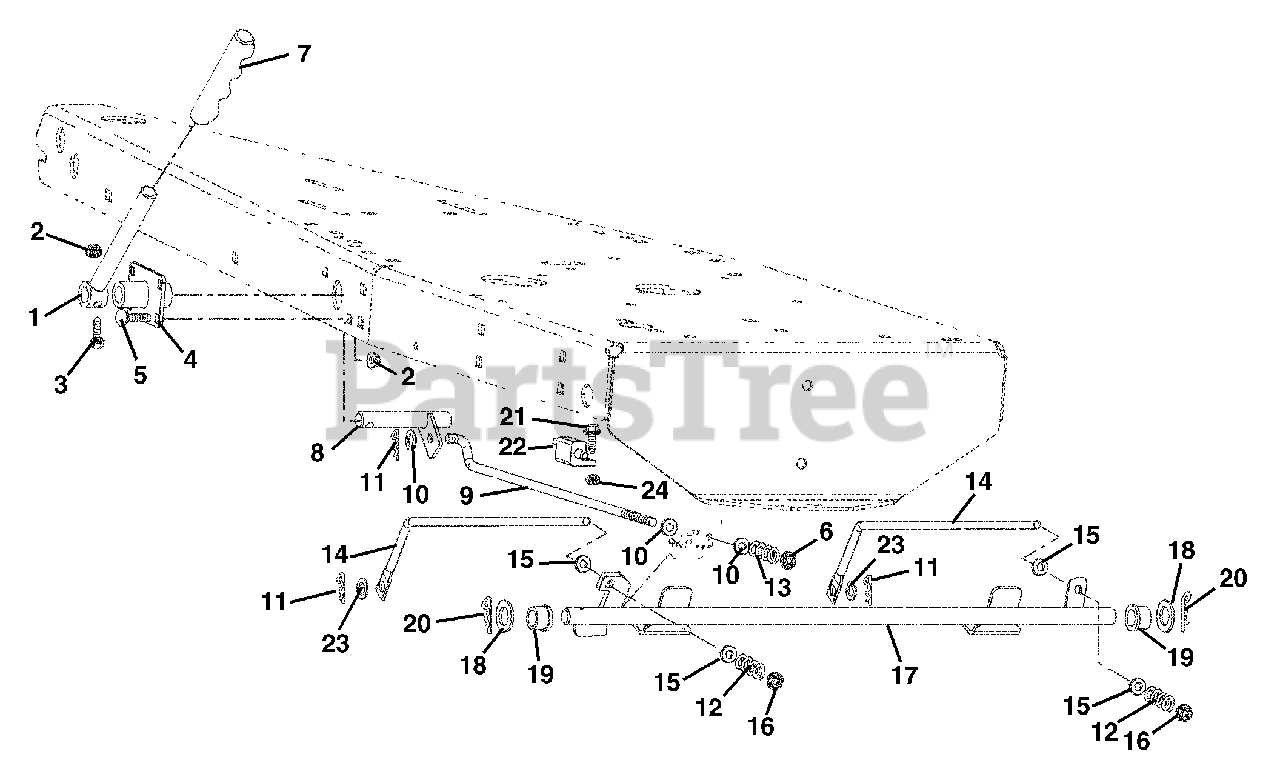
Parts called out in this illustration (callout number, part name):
1	WMT, HANDLE
2	NUT-LK-TOP-FLG .31-18 BLKZC
3	@BLT-HEX .31-18X1.50 GR5 YWZC
4	WMT, HANDLE PIVOT
5	BLT-RDHDSQNK .31-18X.75 G5BZ
6	NUT-LK-TOP-FLG .38-16 BLKZC
8	WMT, PIVOT ARM
9	ROD, ARM-LOCKING
10	@WSHR-FL-STL.406X.812X.065 YWZ
11	PIN-HAIR, ENDRIES #25 YWZC
12	SG-COMP .045X.50X1.187
13	SG-COMP .063X.53X1.187
14	ROD, BRAKE ACTUATING
15	@WSHR-FL-STL.344X.688X.065YWZC
16	@NUT-LK-TOP-FLG .31-18 YWZC
17	SHAFT, BRAKE-WELDMENT
18	WSHR-FL-STL .890X1.500X.1196YZ
19	BSHG-FLG .630X1.000X.625 NY
20	PIN, SPRING CLIP
21	SCR-TAP 10-24X.75 HWH TR YWZC
22	SWITCH- SINGLE POLE N.O.
23	@WSHR-FL-STL.406X.812X.065 YWZ
24	@NUT-LK-NYL 10-24 W/INSRT YWZC
